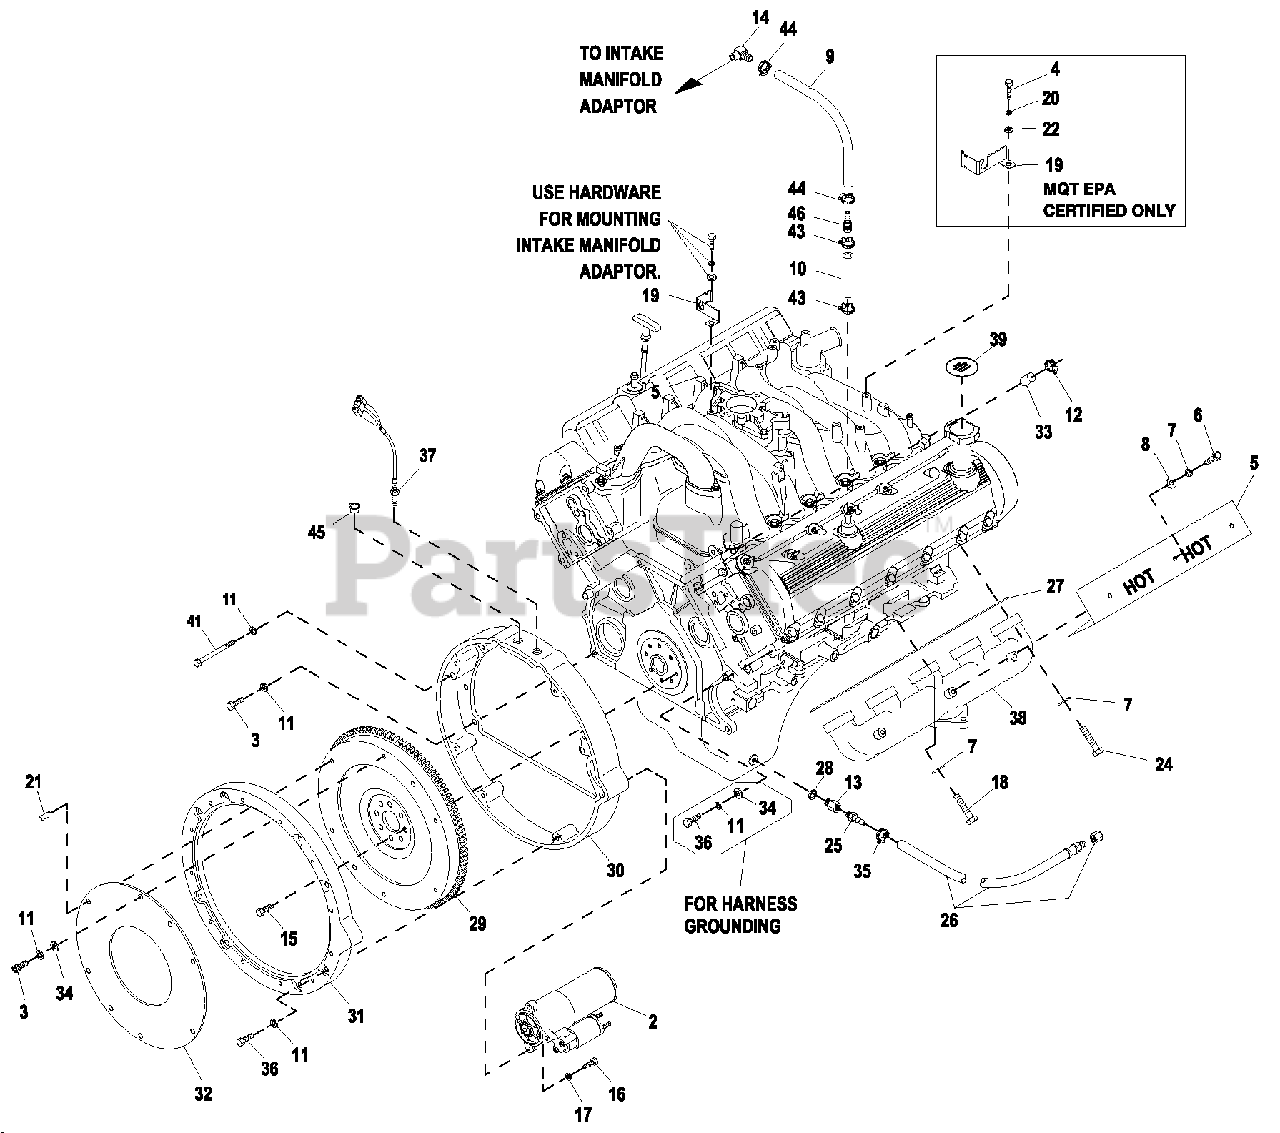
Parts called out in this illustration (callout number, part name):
2	STARTER MOTOR FORD V-10 ENGINE
3	SCREW SHC M10-1.5X35G12.9
4	SCREW HHC M6-1.0 X 16 G8.8
5	HEAT SHIELD EXHAUST
6	SCREW HHC 5/16-18 X 1/2 SSTL
7	WASHER LOCK M8 SSTL
8	WASHER FLAT M8 SS
9	HOSE 3/8 ID SINGLE BRAID
10	HOSE COOL 5/8" ID 250#WP (14")
11	WASHER LOCK M10
12	CLAMP HOSE #10 .56 - 1.06 (2300 & 3000RPM UNITS ONLY)
13	ADAPTER M14-1.50X3/8NPT
14	BARBED EL 90 1/4NPTX 3/8
15	SCREW HHC M10-1.0X 25 G10.9
16	SCREW SHC M8-1.25 X 30 G12.9
17	WASHER LOCK M8-5/16
18	SCREW HHC M8-1.25 X 35 SS F-TH
19	BRACKET SIGNAL CONDITIONER
20	WASHER LOCK M6-1/4
21	DOWEL PIN M10X24
22	WASHER FLAT 1/4 ZINC
24	SCREW SHC M8-1.25 X 35 SS
25	BARBED STR 3/8 NPTX 3/8
26	HOSE DRAIN ASSY 28"
27	GASKET EXHAUST MANIFOLD
28	WASHER NYLON .565
29	ASSEMBLY 6.8L G-BOX FLYWHEEL
30	FLYWHEEL HOUSING MACH 6.8L V10
31	COVER FLYWHEEL MACH 6.8L V-10
32	PLATE DAMPNER RETNR
33	CAP HOSE (2300 & 3000RPM UNITS ONLY)
34	WASHER FLAT 3/8-M10ZINC
35	CLAMP HOSE .38- 87
36	SCREW SHC M10-1.5X25G12.9
37	ASSY MAGPICKUP(3/8-24 MALE)
38	EXH MANIFOLD MACH 6.8L V-10
39	DECAL REFER TO OWNERS MANUAL
41	SCREW SHC M10-1.50 X 100 G10.9
43	CLAMP HOSE BAND .88"
44	CLAMP HOSE BAND .63
45	PLUG PLASTIC 3/8 NPT
46	HOSE BARB REDUCER 5/8"-3/8"ID
